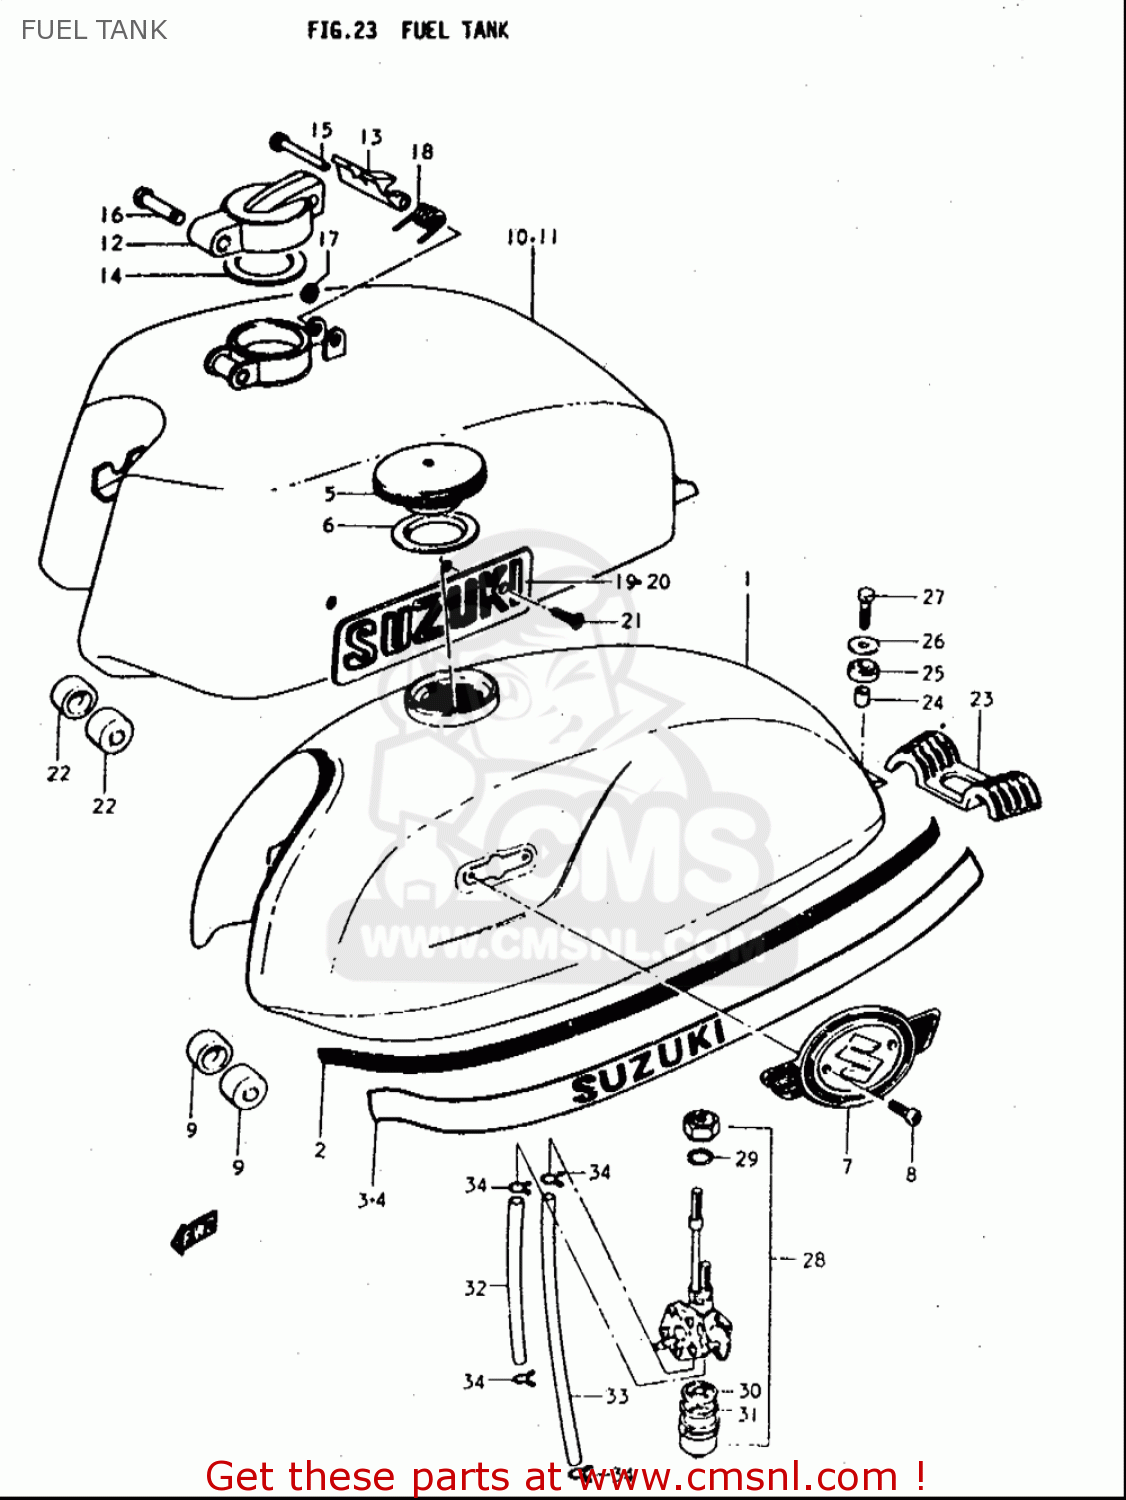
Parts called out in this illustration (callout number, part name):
9	CUSHION
13	LEVER
15	PIN
17	E RING
18	SPRING
22	CUSHION
24	SPACER(8.5X12X11)
25	BUSH(12X15X20)
28	COCK ASSY,FUEL
29	GASKET,FUEL COCK (NAS)
31	GASKET,CLEANER CUP (NAS)
32	HOSE(5X9X600)
34	CLIP
